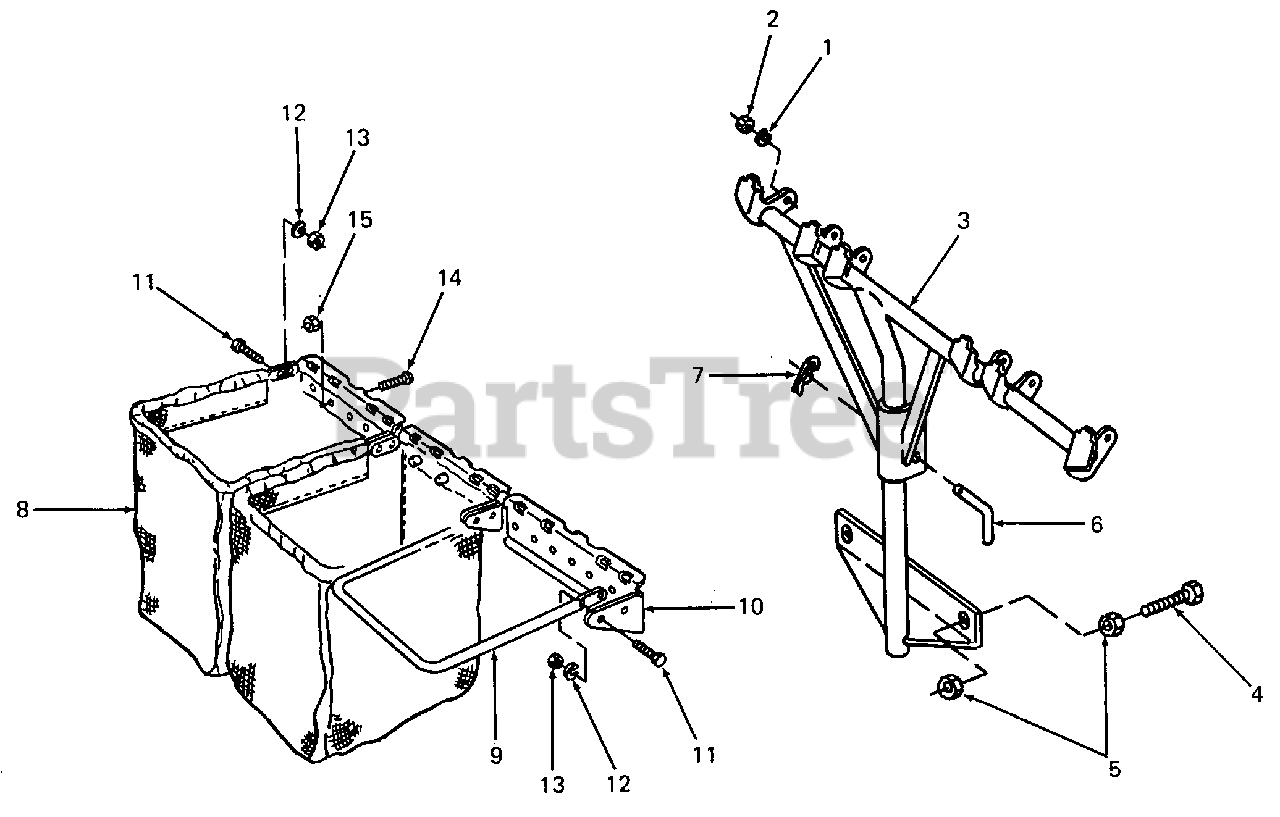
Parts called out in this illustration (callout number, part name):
1	Washer, Lock, 3/8
2	Nut, Hex, 3/8-16
3	Tube Assy, Catcher Support
4	Screw, Hex Cap, 3/8-16 X 1.75 Lg
5	Nut, Hex Jam, 3/8-16 GR5
6	Pin, Right Angle Clevis
7	Pin, Internal Cotter, 5/8 Dia
8	Bag, Grass Catcher
9	Frame, Catcher Bag
11	Screw, Hex Cap, 1/4-28 X .75 Lg
12	Washer, Lock, 1/4
13	Nut, Hex, 1/4-28
14	Screw, Truss Mach, #10-24 X .38 Lg
15	Nut, Hex Sems, #10-24
